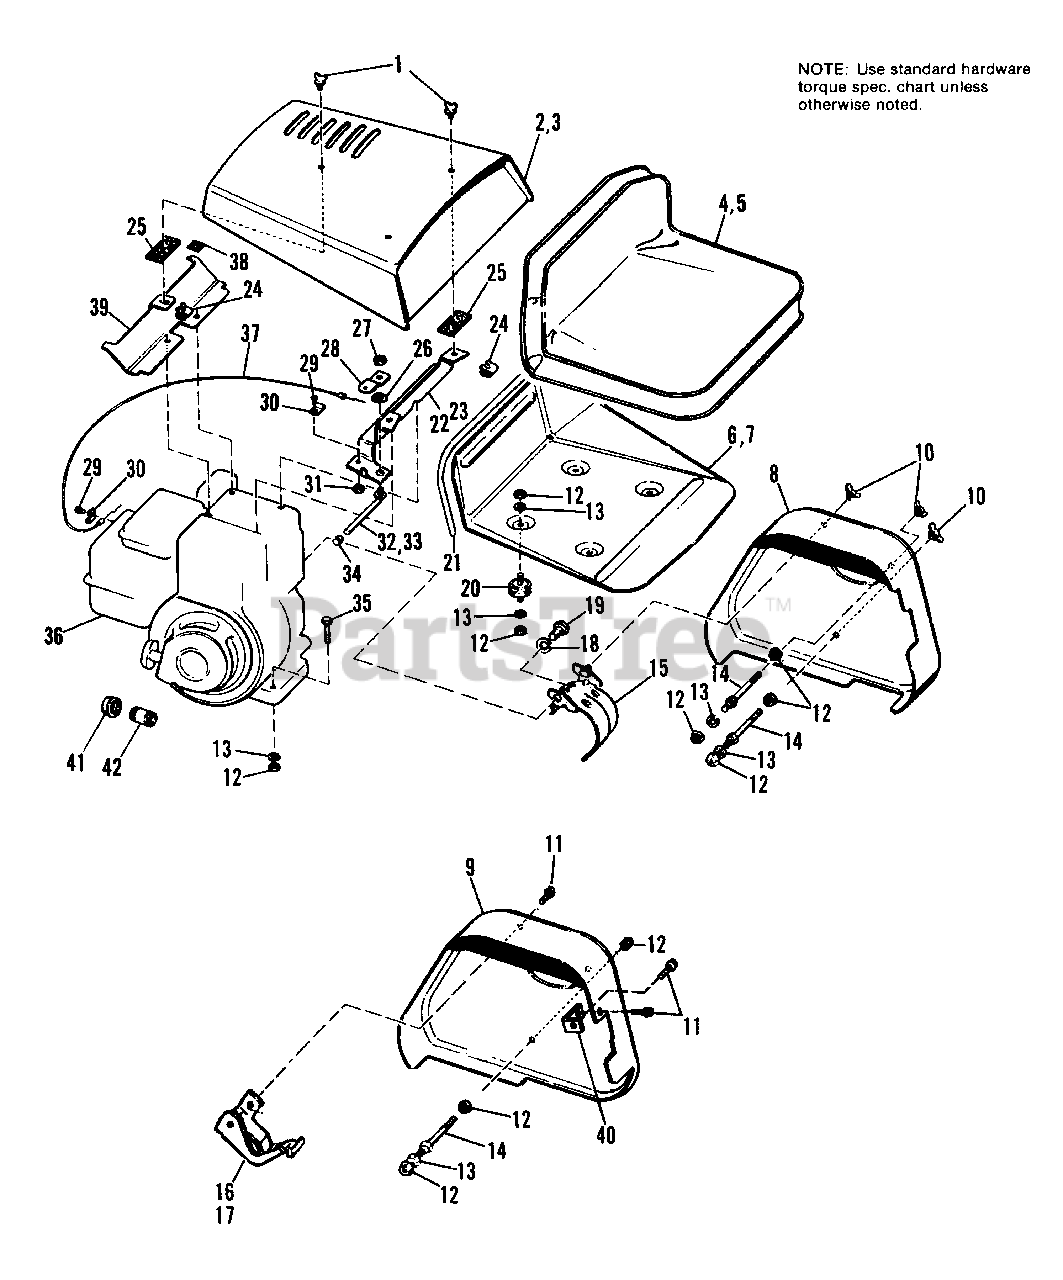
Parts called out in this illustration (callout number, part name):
1	SCREW, Thumb, 5/16-18 x 3/4
2	HOOD ASSY.
3	HOOD ASSY.
4	PAD, Seat
5	PAD, Seat
6	PANEL, Seat
7	PANEL, Seat
8	GUARD, Pulley
9	GUARD, Pulley
10	NUT, Wing, 5/16-18
11	SCREW, Taptite, 5/16- 18 x 1/2
12	NUT, Hex, Full, 5/16-18
13	LOCKWASHER, 5/16 (Qty. 13 used on 990554, 990614, 990774, 990775)
14	STUD (Qty. 1 on 990554, 990614, 990774, 990775)
15	STOP ASSY., Belt
16	STOP ASSY., Belt (Used on 990554 & 9907714)
17	STOP, Belt (Used on 990614 Only)
18	LOCKWASHER, 1/2
19	CAPSCREW, Hex Hd., 1/2-20 x 3/4
20	CONNECTOR, Cushion
21	TAPE, 2 ft.
22	SUPPORT, Hood, Front
23	SUPPORT, Hood, Front (Used on 990774, 9910775)
24	NUT, Retainer
26	WASHER, Throttle
27	LOCKNUT, Hex, 3/8-16
28	ARM, Throttle
29	SCREW, Machine, Rd. Hd., #10-32 x 3/8
31	NUT, Hex, Full, #10-32
32	HANDLE, Throttle Control
33	HANDLE, Throttle Control
35	CAPSCREW, Hex Hd., 5/16-18 x 1-1/2
37	CABLE & WIRE ASSY.
38	GASKET, Felt
39	SUPPORT, Hood, Rear
40	BRACKET, Pulley Guard
41	CAP, Pipe, Nipple
42	NIPPLE, Pipe
